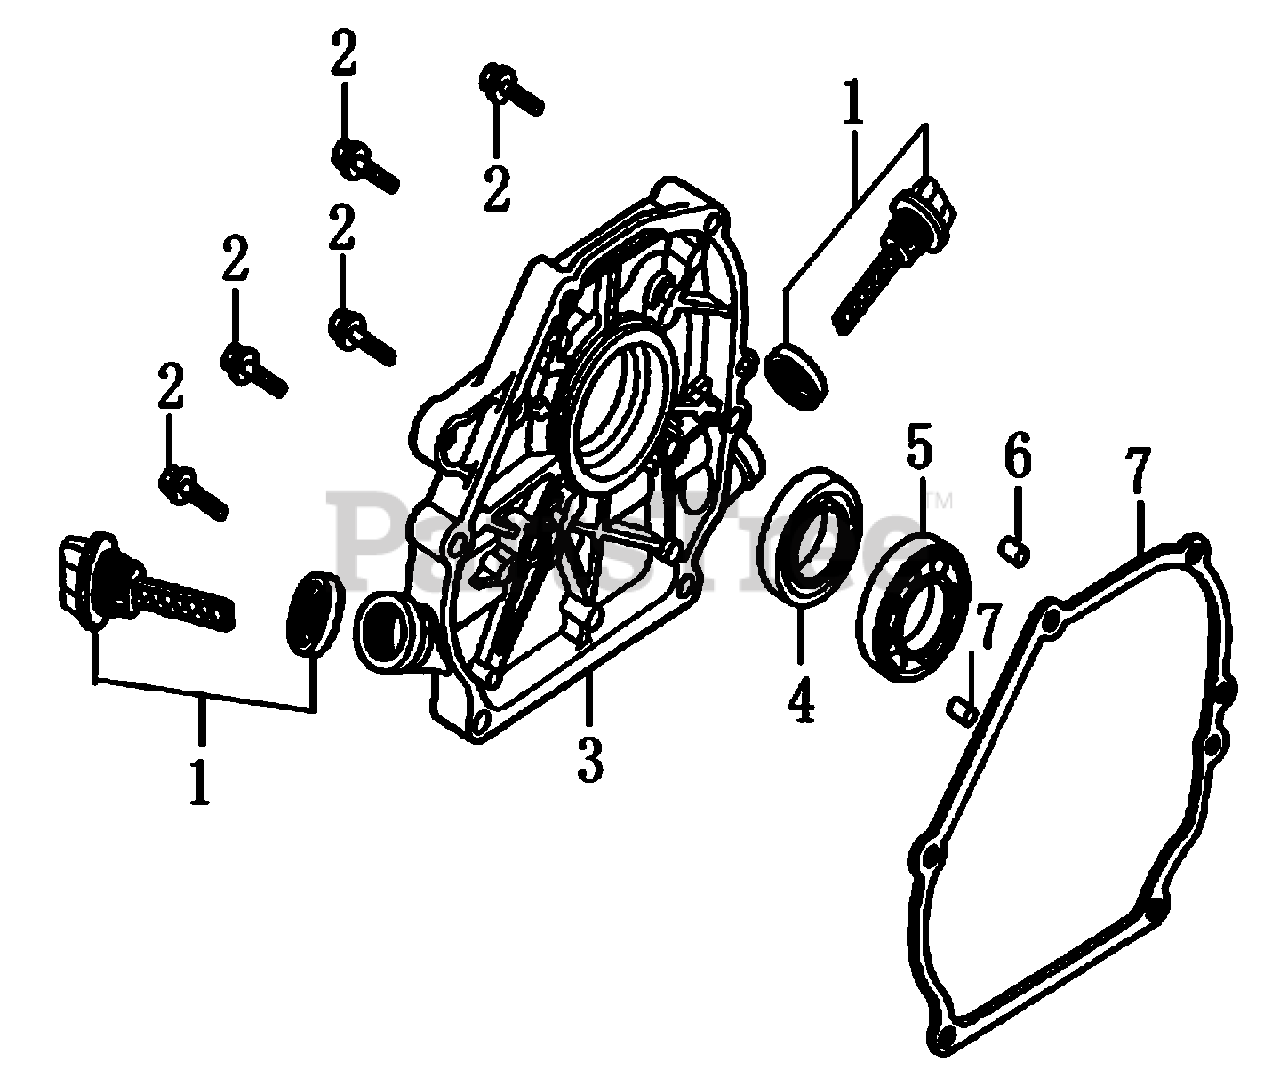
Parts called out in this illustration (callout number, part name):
1	GAUGE ASSY.,OIL LEVEL
2	BOLT, FLANGE
3	CASE COVER
4	OIL SEAL 25X41.25X6
5	BEARING, RADIAL BALL
6	PIN, DOWEL
7	GASKET, CASE COVER
